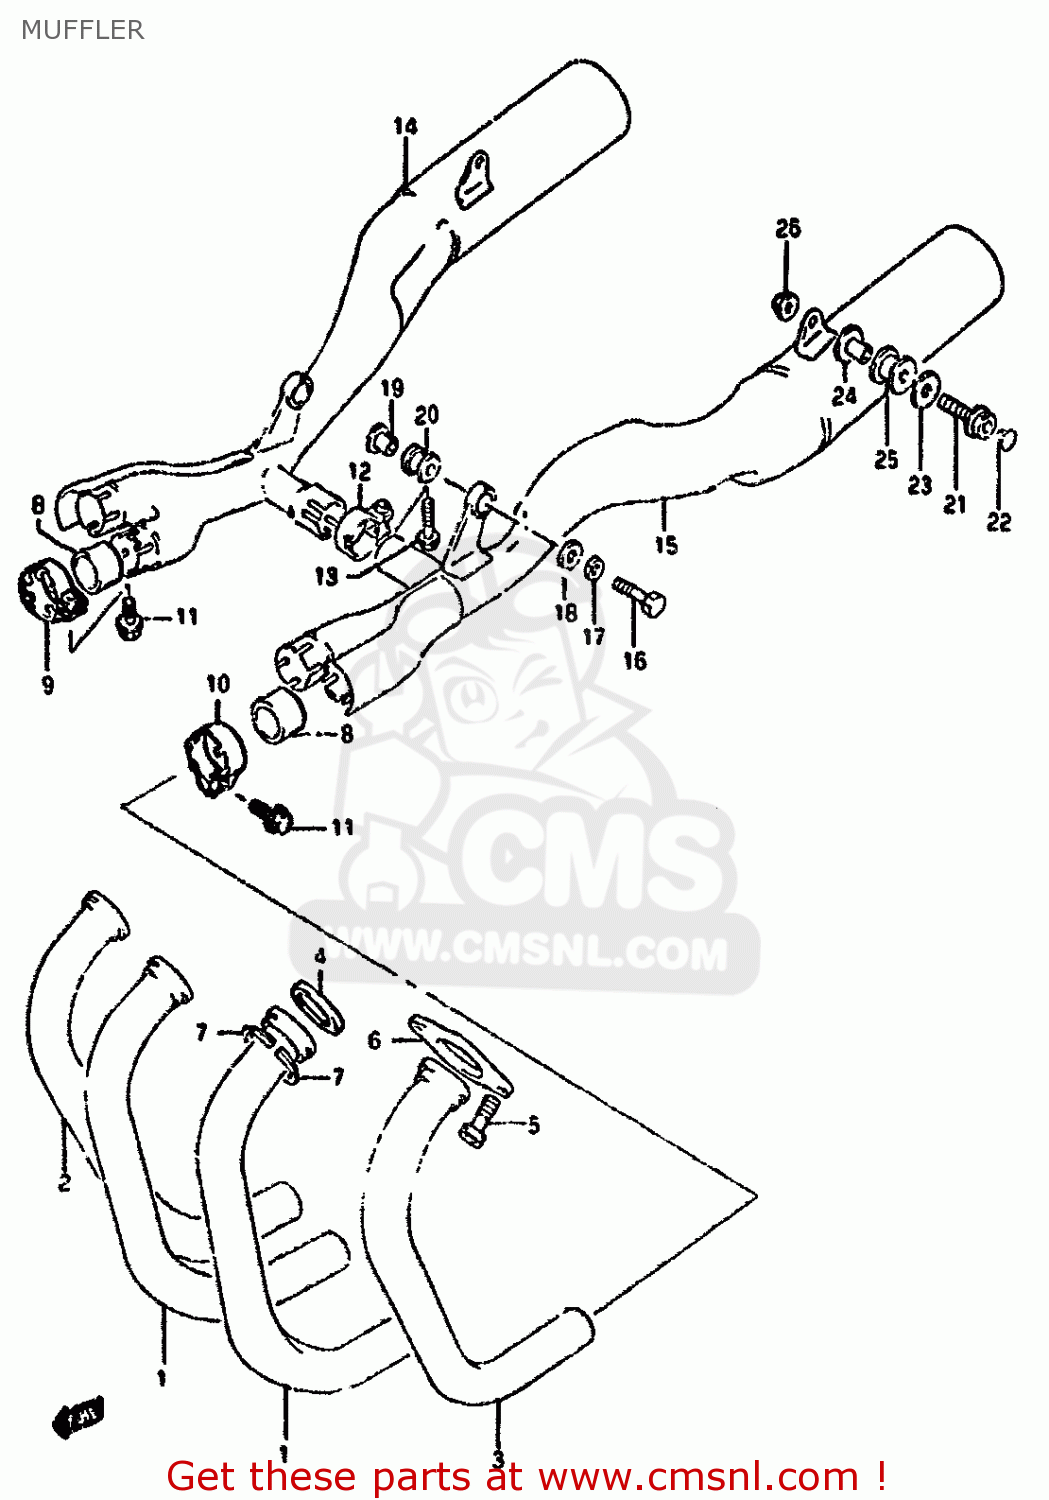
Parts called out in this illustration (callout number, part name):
1	PIPE,EXHAUST,CENTER
2	PIPE,EXHAUST,RIGHT
3	PIPE,EXHAUST
4	GASKET,EXHAUST (NAS)
5	BOLT
6	CLAMP,EXHAUST PIPE
7	PLATE,EXHAUST PIPE
8	CONNECTOR,MUFFLER
9	CLAMP,MUFFLER CONNECTOR,R
10	CLAMP,MUFFLER CONNECTOR,L
11	BOLT
12	CLAMP,MUFFLER JOINT
13	BOLT
14	MUFFLER,RH
15	MUFFLER,LH
16	BOLT
17	LOCK WASHER
18	WASHER (8.5X20X1.6)
19	SPACER(8.6X12X18.5)
20	CUSHION
21	BOLT
22	CAP(OD:10)
23	WASHER (8.5X30X2.3)
24	SPACER(8.6X12X27.1)
25	CUSHION
26	NUT
